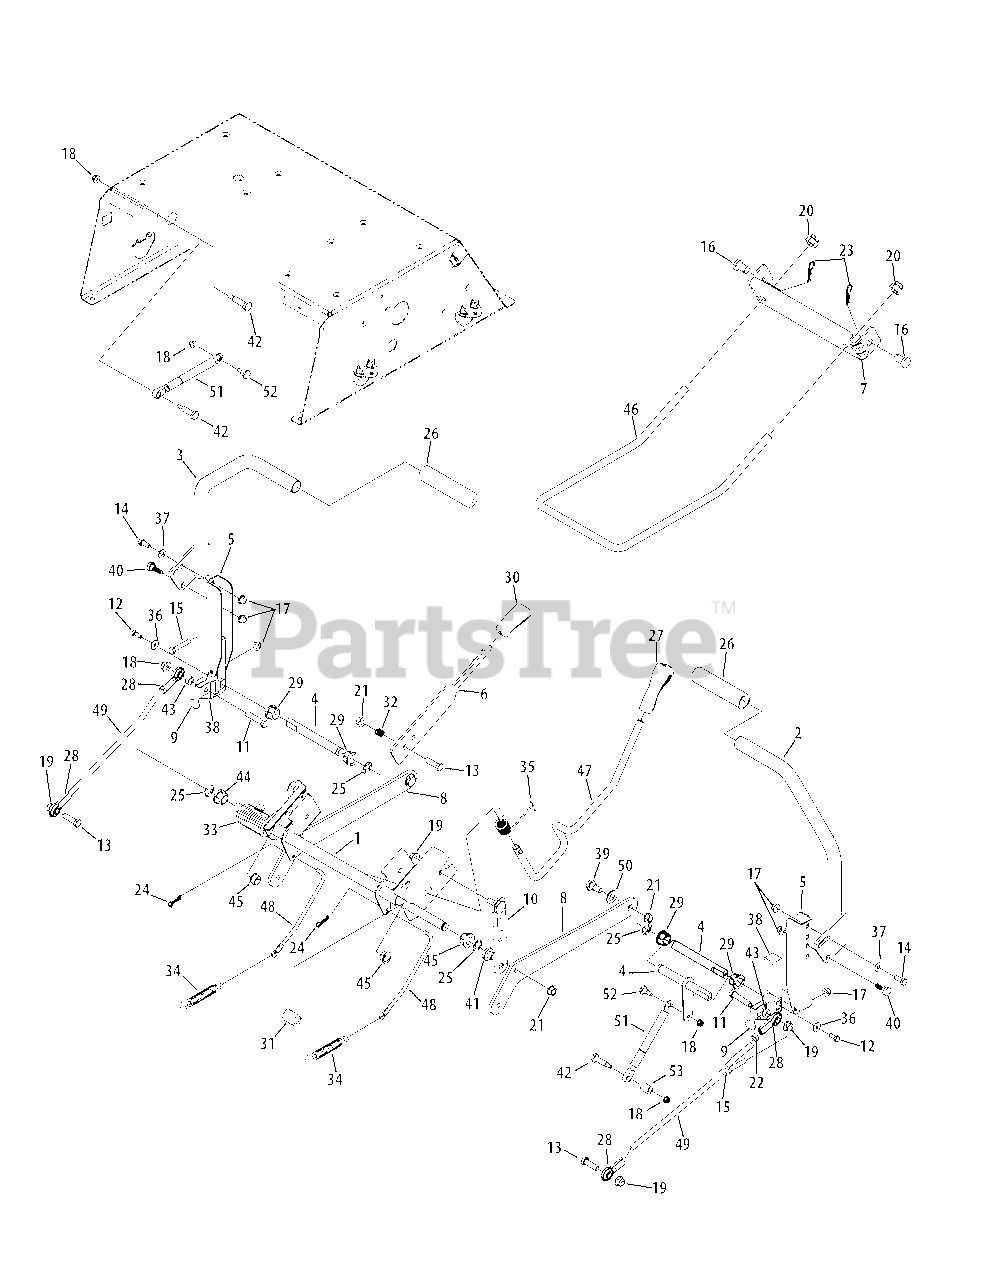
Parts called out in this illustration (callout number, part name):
1	Deck Lift Shaft Assembly
2	RH Lapbar Lever Assembly
3	LH Lapbar Lever Assembly
4	Shaft Control
4	Shaft Control, Dampers
5	Lapbar Pivot Bracket
6	Brake/Shabs Handle
7	Front Deck Hanger Bracket
8	Deck Lift Arm Plate
9	Actuator Switch Bracket
10	Link Lift Plate
11	Hex Screw, 3/8-16 x 1.75
12	Hex Lock Screw, 1/4-20 x .625
13	Hex Screw, 3/8-16 x 1.25
14	Hex Screw, 5/16-18 x .75
15	Hex Screw, 5/16-18 x 1.75
16	Clevis Pin, .50 x .78
17	Flange Lock Nut, 5/16-18
18	Flange Lock Nut, 1/4-20
19	Flange Lock Nut, 3/8-16
20	Flex Lock Nut, 1/2-13
21	Hex Lock Nut, 3/8-16, Centerlock
22	Jam Nut, 3/8-24
23	Internal Cotter Pin, .080 x 1.5625
24	Bow-Tie Cotter Pin
25	E-Ring, .625
26	Grip, 1.0 x 5.0
27	Handle Grip, 1/2
28	B/Joint Rode End, .375
29	Hex Flange Bearing, .629
30	Selector Handle
31	Spacer, .62 x 1.00
32	Compression Spring, .50 x .50
33	Torsion Spring, 1.19 x 2.78
34	Extension Spring, .59 x 4.00
35	Torsion Spring
36	Bell Washer, .265 x .75 x .062
37	Flat Washer, .344 x .688 x .065
38	PM Control Hub
39	Shoulder Bolt, 3/8-16 x .496 x .336
40	Shoulder Screw, 5/16-18 x .437 x .268
41	Shoulder Screw, .500 x .434
42	Shoulder Screw, .374 x 1.16
43	Spacer, .380 x .625 x .255
44	Hex Flange Bearing
45	Flange Bearing, .626 x .938 x .344
46	Deck Lift Frong Hanger Rod
47	Deck Lift Handle Rod
48	Brake Rod
49	Lapbar Rod Control
50	Flat Washer, .510 x 1.00 x .060
51	Damper Cylinder
52	Shoulder Screw, .375 x .38 x 1/4-20
53	Spacer, .385 x .630 x .75
